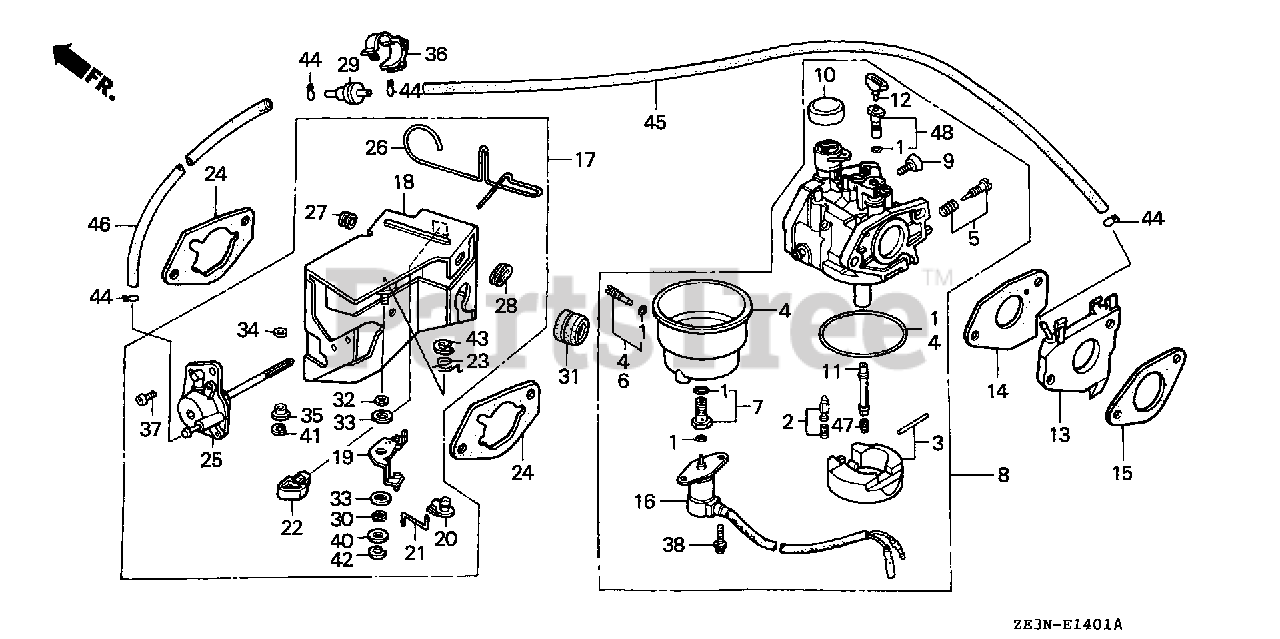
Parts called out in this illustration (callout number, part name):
1	GASKET SET
2	VALVE SET, FLOAT
3	FLOAT SET
4	CHAMBER SET, FLOAT
5	SCREW SET
6	SCREW SET, DRAIN
7	SCREW SET B
8	CARBURETOR ASSY. (BE82B B)
9	SCREW, THROTTLE STOP
10	CAP, CHOKE LEVER DUST
11	NOZZLE, MAIN
12	COLLAR, SET
13	INSULATOR, CARBURETOR
14	GASKET, CARBURETOR
15	GASKET, INSULATOR
16	VALVE ASSY., SOLENOID
17	STAY ASSY., MANUAL CHOKE
18	STAY, SOLENOID
19	LEVER, CHOKE
20	JOINT, ROD
21	ROD, CHOKE
22	STOPPER, CHOKE ROD
23	SPRING, MANUAL CHOKE
24	GASKET, AIR CLEANER
25	DIAPHRAGM ASSY.
26	ROD, CHOKE CONTROL
27	GROMMET, CHOKE ROD
28	GUIDE, CHOKE ROD
29	VALVE, DASHPOT CHECK
30	BUSH, ARM PIVOT
31	GROMMET, FENDER
32	WASHER, CHOKE LEVER
33	SEAL, CHOKE LEVER
34	WASHER, THRUST (2.7X8)
35	COLLAR, LEVER
36	CLIP, WIRE HARNESS
37	SCREW, PAN (5X12)
38	SCREW-WASHER (5X12)
40	WASHER, PLAIN (5MM)
41	E-RING (2MM)
42	E-RING (4MM)
43	E-RING (7MM)
44	CLIP, TUBE (B7)
45	BULK HOSE, VACUUM (3.5X8000) (3.5X75)
46	BULK HOSE, VACUUM (3.5X8000) (3.5X130)
47	JET, MAIN (#95)
47	JET, MAIN (#98)
47	JET, MAIN (#100)
48	JET SET, PILOT (#35)
